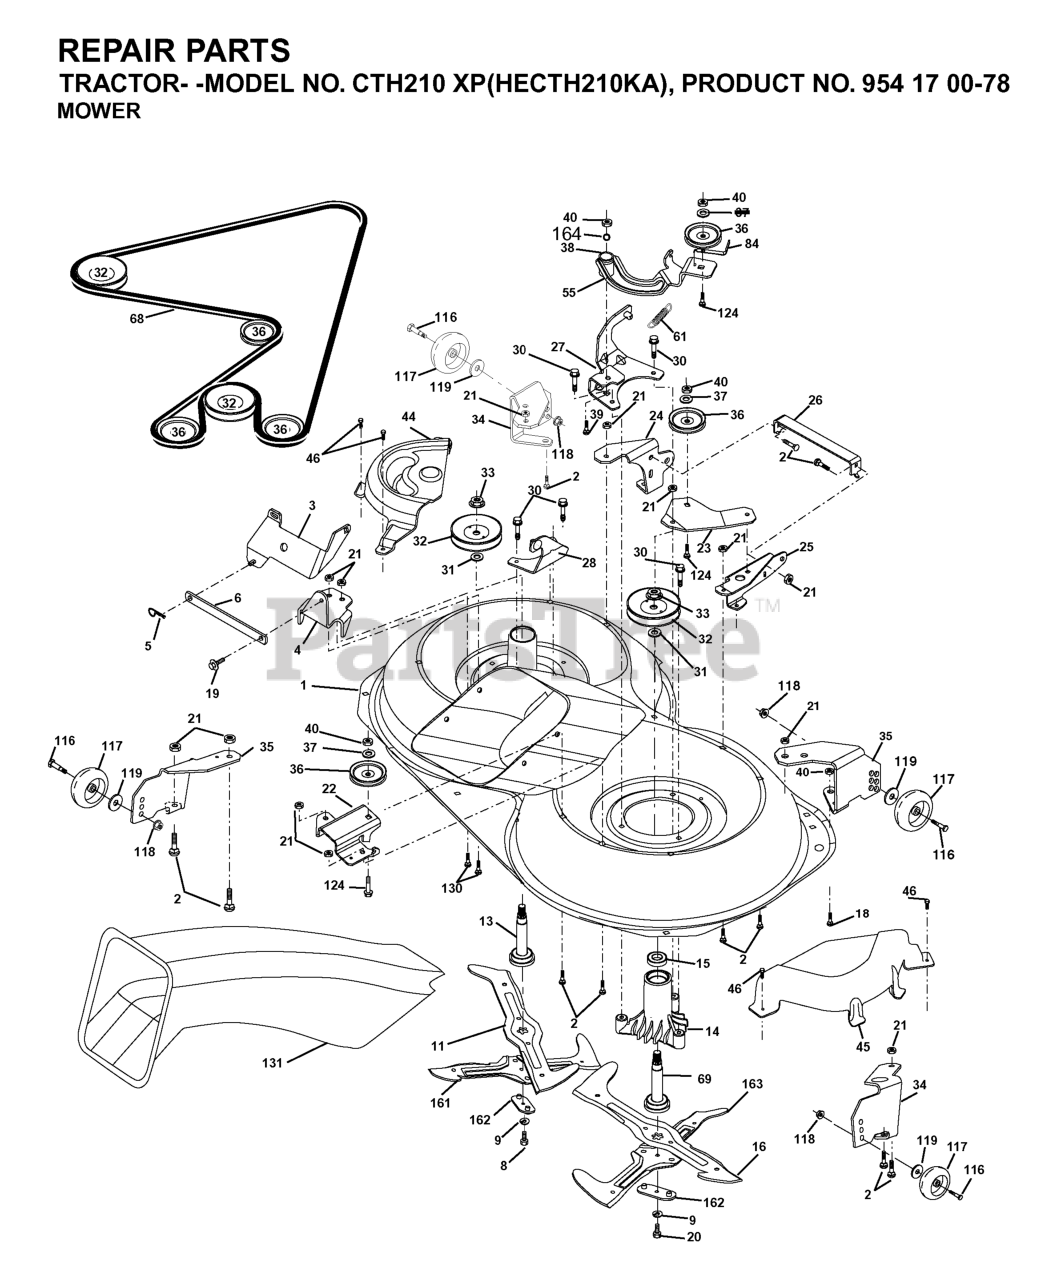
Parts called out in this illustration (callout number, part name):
1	Housing Asm. Mower 107 CRD
2	RP BOLT 5/16-18 X3/4 ZN/YEL GR
5	RETAINER SPRING
5	RETAINER-SPRNG RB
6	BAR.SWAY.92.CRD
8	BOLT.3/8-24X1.25 GR8
9	LOCKWASHER
11	BLADE.3N1.LH.CRD
13	SHAFT ASM VENT
14	HOUSING.MANDREL.VENTED (MACHD)
16	BLADE.3N1.RH.CRD
18	BOLT D
19	BOLT SHD 5/16-18
20	BOLT.3/8-24X1.25GR8. LHTHRD
21	LOCKNUT
22	BRACKET.IDLER.RR.107.CRD
25	BRACKET.SUSPENSION.RF.107.CRD
26	BRACE.SUPT.SUSP.FRT.CRD
28	BRACKET
30	SCREW, WASHER HEAD
31	WASHER.SPACER.MANDREL
33	NUT, FLG TOPLOCK 9/16"
36	PULLEY.IDLER.4.25
40	NUT LOCK FLG 3/8-16 UNC
45	COVER.MANDREL.RH.CRD
46	SCREW.1/4-20X5/8
55	ARM.IDLER.107.CRD
68	HEX-BELT 107 MOWER
69	SHAFT.ASM.W/LWR.BRG.RH.THREAD
84	KEEPER, BELT IDLER
116	SHOULDER BOLT
117	WHEEL GAGE DONUT
118	LOCKNUT
119	WASHER.5/16.FLAT.STE.STD.
124	BOLT.3/8-16X1.50
130	BOLT.CARR.SQNK.5/16-18UNC.X3/4
131	CHUTE BAGGER
163	BLADE.CROSS.RH.CRD.107
164	BRNG T
